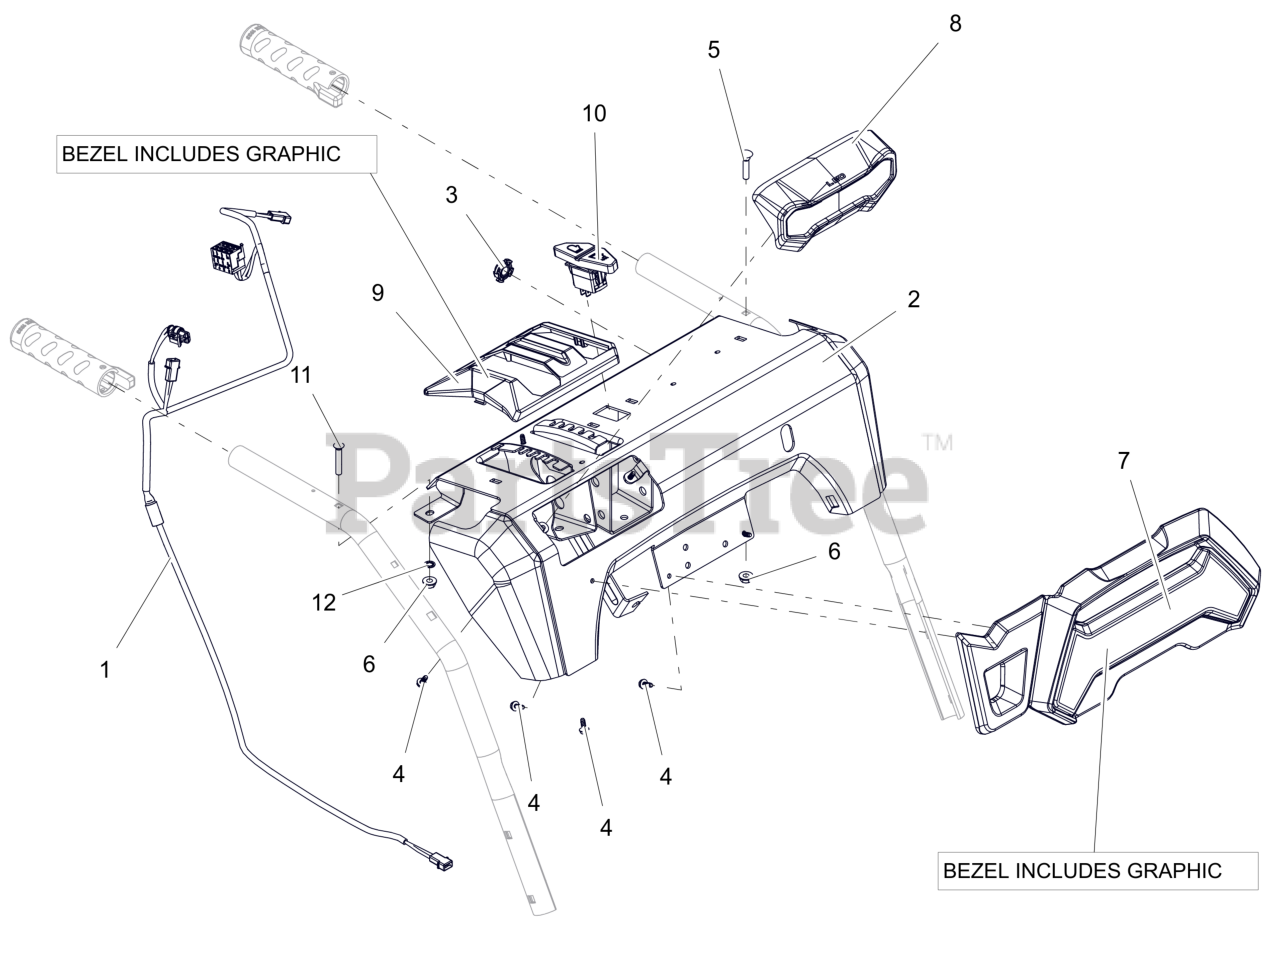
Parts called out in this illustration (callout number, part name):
1	HARNESS- WIRE - LT HG
2	PANEL, DASH W/SAFETY DECALS
3	CRANK BUSHING, NYLON CHUTE BK
4	SCR, PLASTIC #10X.50
5	BLT-RDHDXLSQNK.25-20X1.25 G5ZC
6	NUT-LK-CTR-FLG .25-20 ZC120
7	BEZEL, LARGE - DELUXE
8	HEADLIGHT ASM- LED
9	BEZEL, SHIFT - FRICTION
10	SWITCH- ROCKER SPST-ON/OFF
11	SCR,OVAL .25-20X1.50 ZCC
12	WSHR-LK-INT .250 TH TYA
